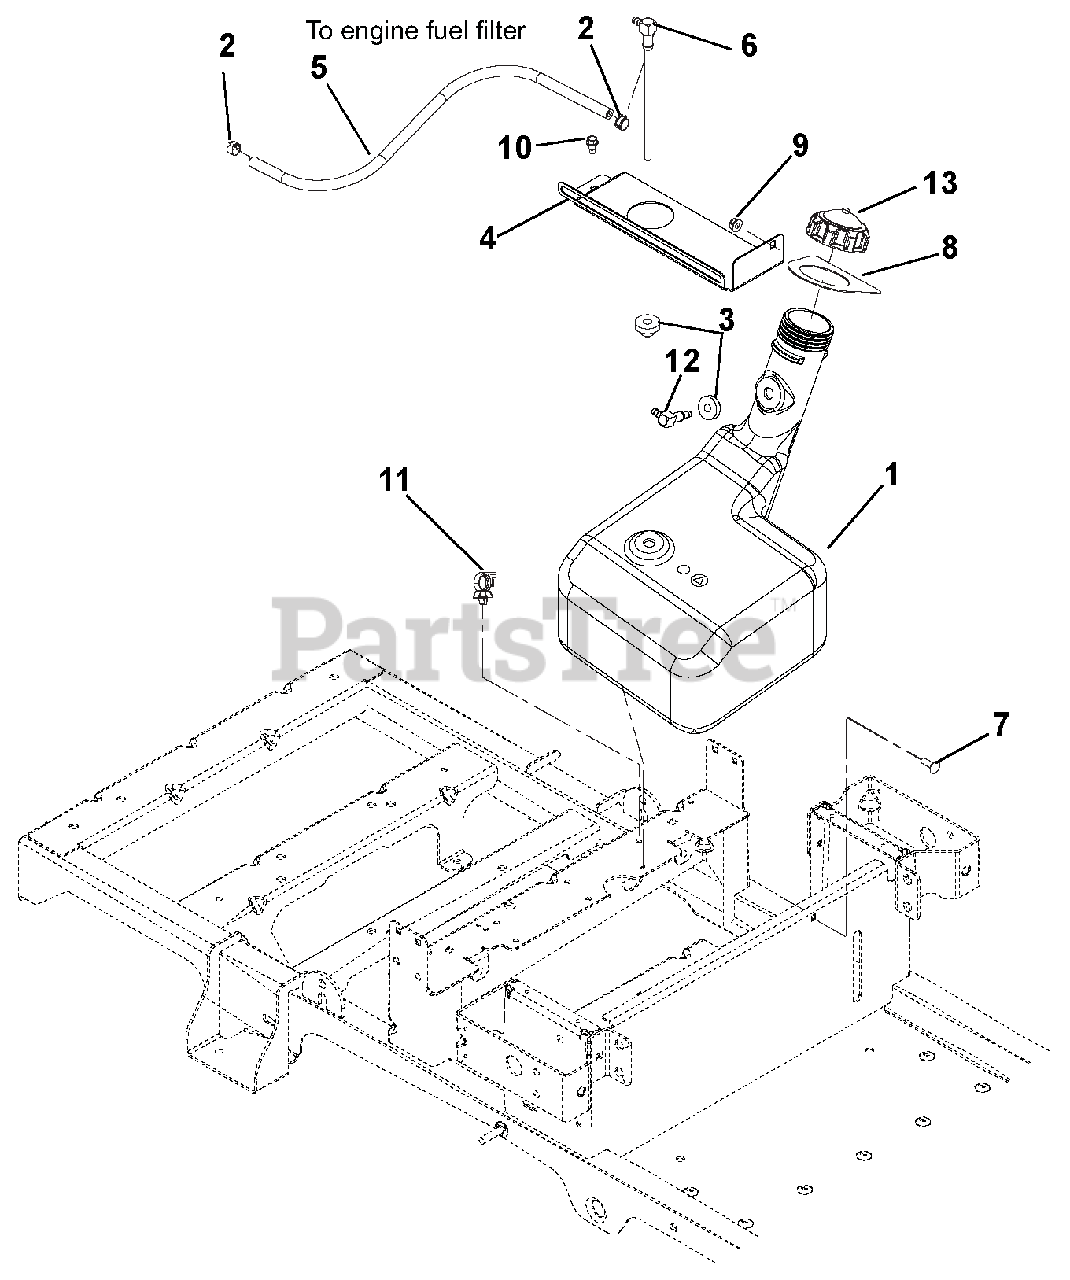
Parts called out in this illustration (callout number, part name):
1	TANK, ZOOM/WAW NON-PERM. FUEL
2	CLAMP, FUEL LINE
3	BSHG-FLG .375X1.062X.625 NITR
4	BRKT, TANK STRAP
5	HOSE, .25 LOW-PERM BULK GAS
6	FUEL PICK UP TUBE
7	@BLT-RDHDSQNK .25-20X.75 G5YZ
8	SEAL-TANK NECK
9	@NUT-LK-NYL-FLG .25-20 YWZC
10	SCR-TAP .25-20X.50 HWH TR YWZ
11	WIRE CLIP
12	FITTING, 90 DEG FUEL-PLASTIC
13	CAP, 2.25" ONE-WAY VENT FUEL
